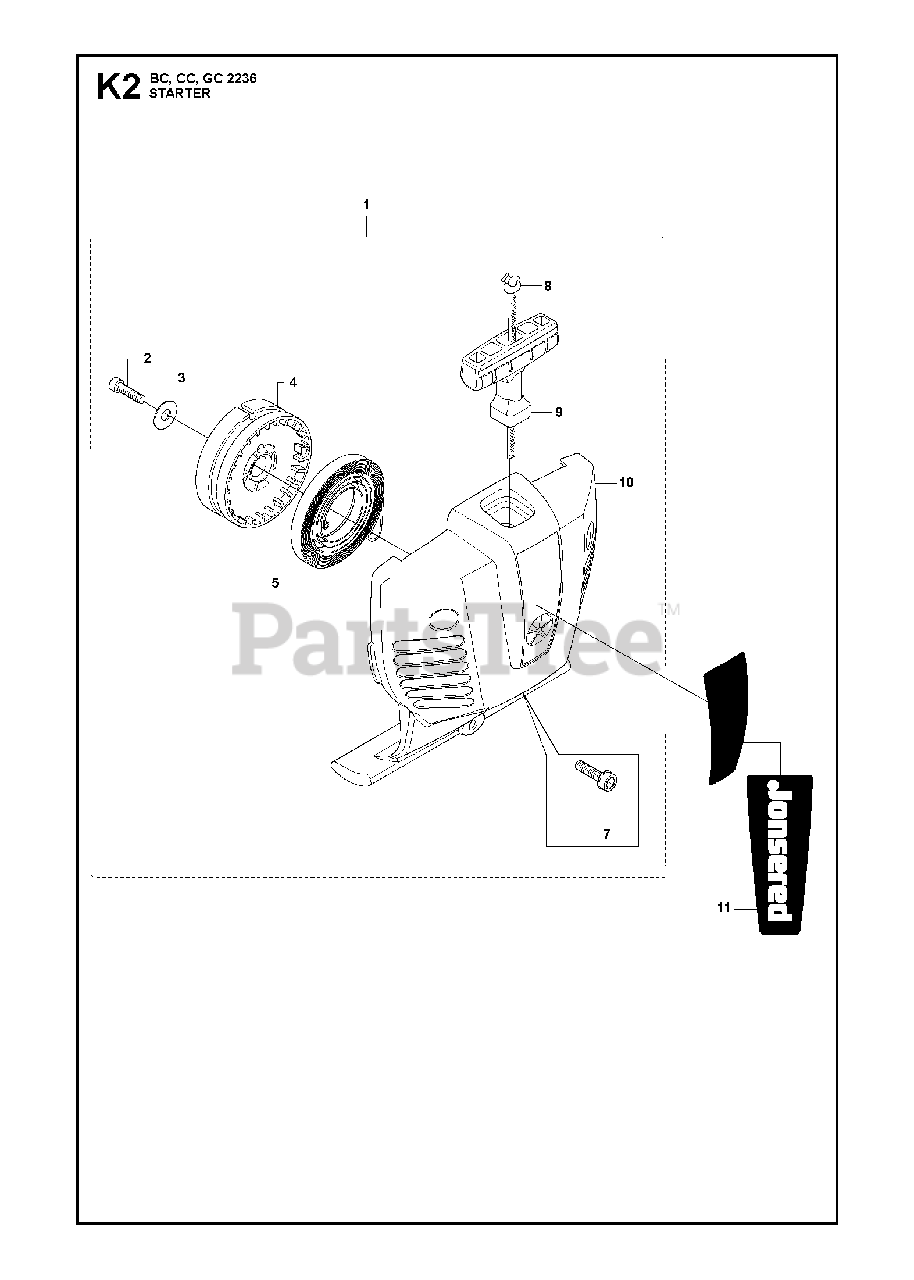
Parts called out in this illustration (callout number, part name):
1	STARTER HOUSING
2	SCREW
3	WASHER
4	%STARTER PULLEY
5	STARTER SPRING
7	SCREW IHSCFMO
8	STARTER ROPE
9	HANDLE
10	STARTER HOUSING
